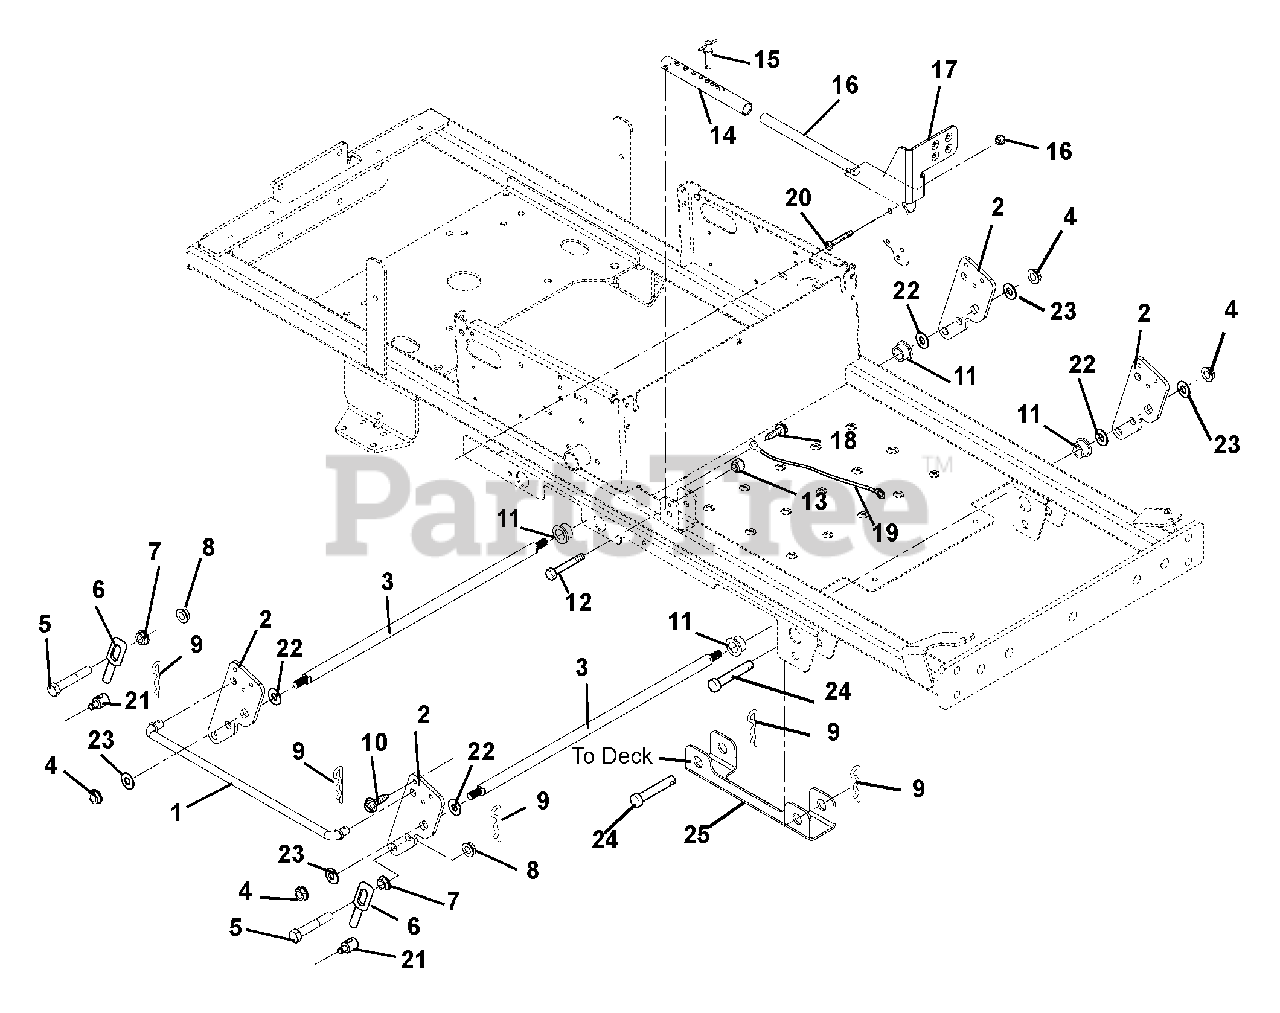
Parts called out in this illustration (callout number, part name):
1	Rod, Lift
2	Lift Arm
3	Shaft, Lift
4	Nut, Hex .250-28
5	Bolt, Hex .50-13 x 2.75 Grade 8
6	Deck Link
7	Nut, Spin Lock Flange .50-13
8	Nut .50-13 Nyloc Flange
9	Pin, Hair #16
10	Screw, Tap .31-18 x .50
11	Bushing, Flange .750 x 1.000 x .625 x 1.250
12	Bolt, Hex .38-16 x 2.00 Grade 5
13	Nut, Flange Nyloc 3/8-16
14	Tube, Lift Stop
15	Pin, Spring Ball .375OD x 1.50
16	Rod, Lift
17	Pedal, Foot Lift
18	Screw, Tap .25-20 x .50
19	Cable, Hood
20	Bolt, Hex .38-16 x 2.50 Grade 5
21	Trunnion
22	Washer, Flat Steel .755 x 1.375 x .062
23	Washer, Flat-Steel .515 x 1.625 x .250
24	Pin-Clevis .494 x 2.50
25	Channel, Deck Lift
